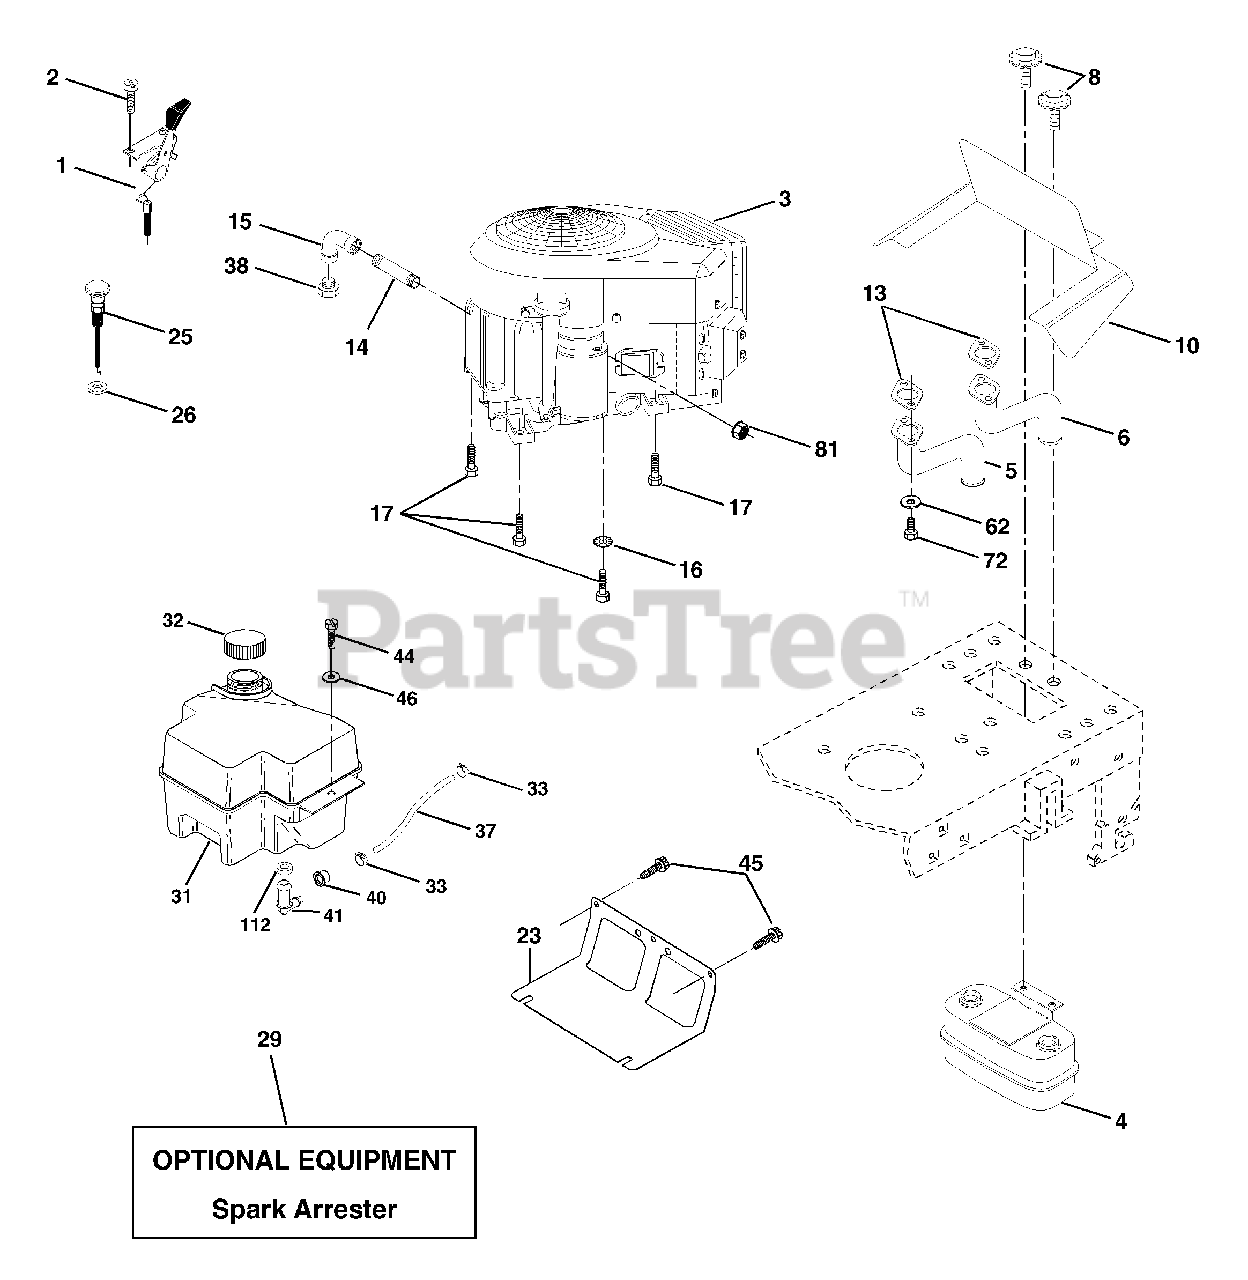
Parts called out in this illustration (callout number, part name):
1	Control, Throttle
2	Screw Hex Thd Cut 1/4-20 x 1/2
4	Muffler, Asm. Twin Lo-Tone
5	Pipe Exhaust Intek 20 RH
6	Pipe Exhaust Intek 20 LH
8	Bolt 5/16-18 UNC x 3/4 w/Sems
10	Shield Browing B&S Intek II
13	Muffler Gasket
14	Nipple Pipe 3/8 NPT x 3"
15	Elbow Std 90 Degree 3/8-18 NPT
16	Washer, Lock Ext tooth 3/8
17	Screw 3/8-16 x 1-1/2
23	Shield, Browning/Debris Guard
25	Control Choke
26	Nut Keps 3/8-24 UNF
29	Arrester, Spark
31	Tank, Fuel
32	Cap Gauge, Fuel
33	Clamp, Hose Blk
37	Line, Fuel 7.5
38	Plug Drain Oil
40	Bushing Snap Nyl Blk Fuel Line
41	Stem Tank Fuel
44	Screw Hex Wsh Thdrol 1/4-20 x 3/4
45	Screw Hex Wsh Thdrol 3/8-16 x 3/4
46	Washer 9/32 x 7/8 x 16 Ga.
62	Washer Lock Hvy Hlcl Spr 5/16
72	Screw Hex Hd Cap 5/16-18 x 3/4
81	Nut Keps Hex 1/4-20 Unc
112	Bushing
